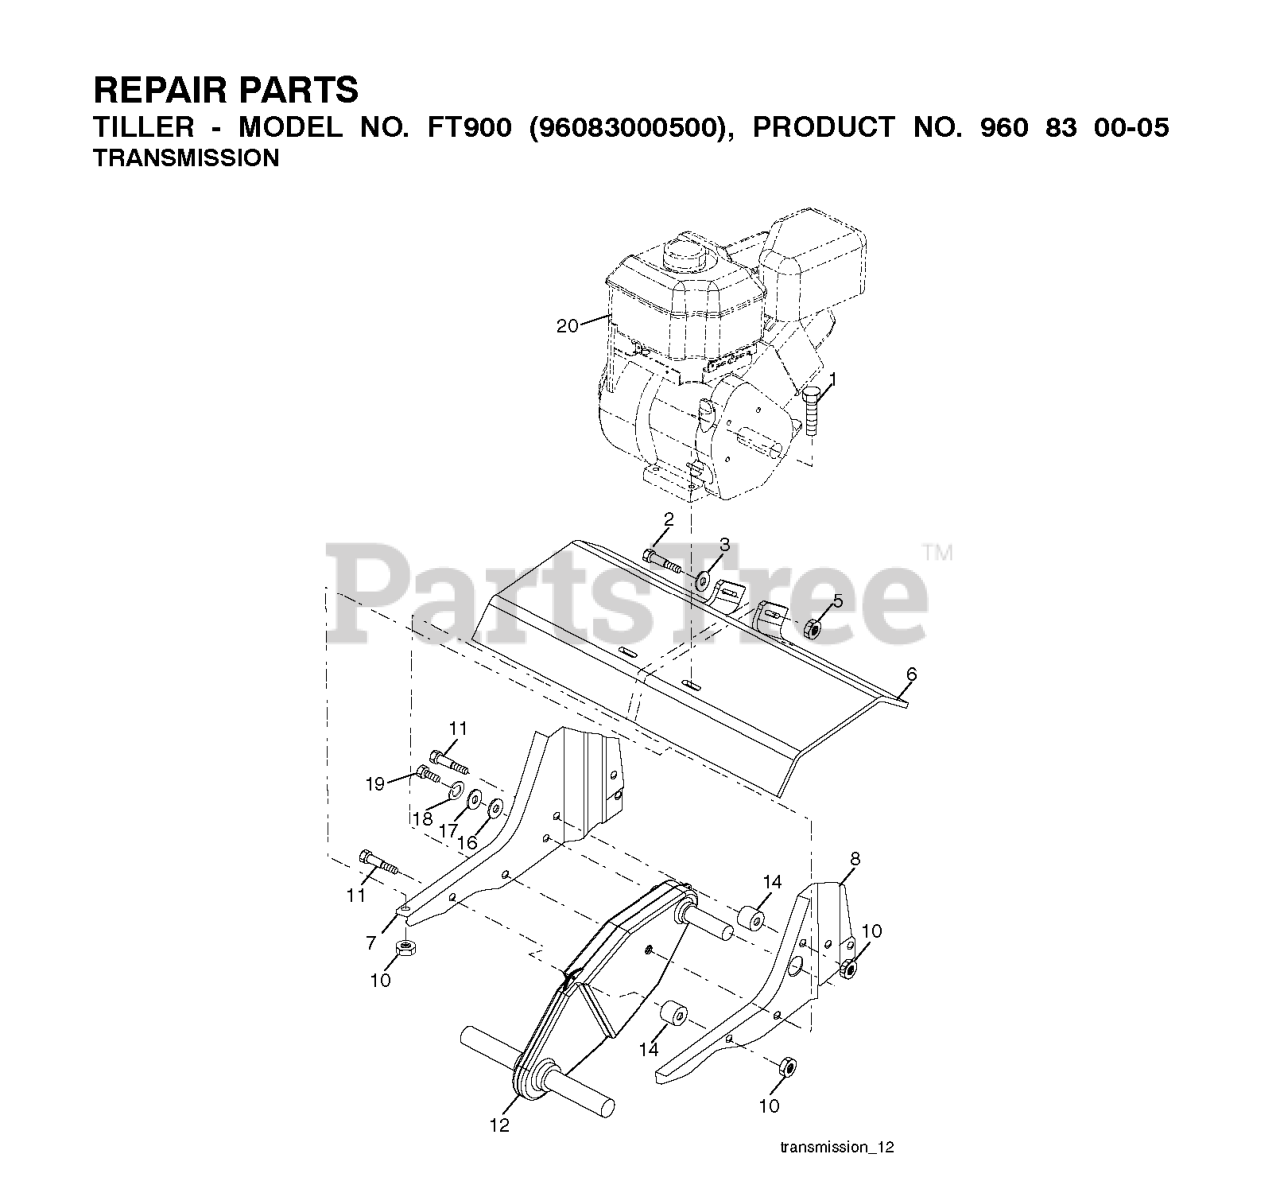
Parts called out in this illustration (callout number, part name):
1	BOLT
2	Bolt, Hex 3/8-16 x 3-1/4
3	WASHER
5	NUT LOCK FLG 3/8-16 UNC
6	SHIELD.PNT.TINE.24".ORANGE
7	RP.BRACKET.ENGINE.RH.TILLER.BL
8	BRACKET.ENGINE.TILLER.LH.BLACK
10	LOCKNUT-FLANGE 5/16-18
11	BOLT, HEX HEAD 5/16-18 X 2.5
12	TRANSMISSION.ASM.W/1".D-SHAFT
16	REPL BY 819 09 14-16
18	LOCKWASHER
19	Bolt, Hex 1/4-28 x 3/4 Gr. 5
